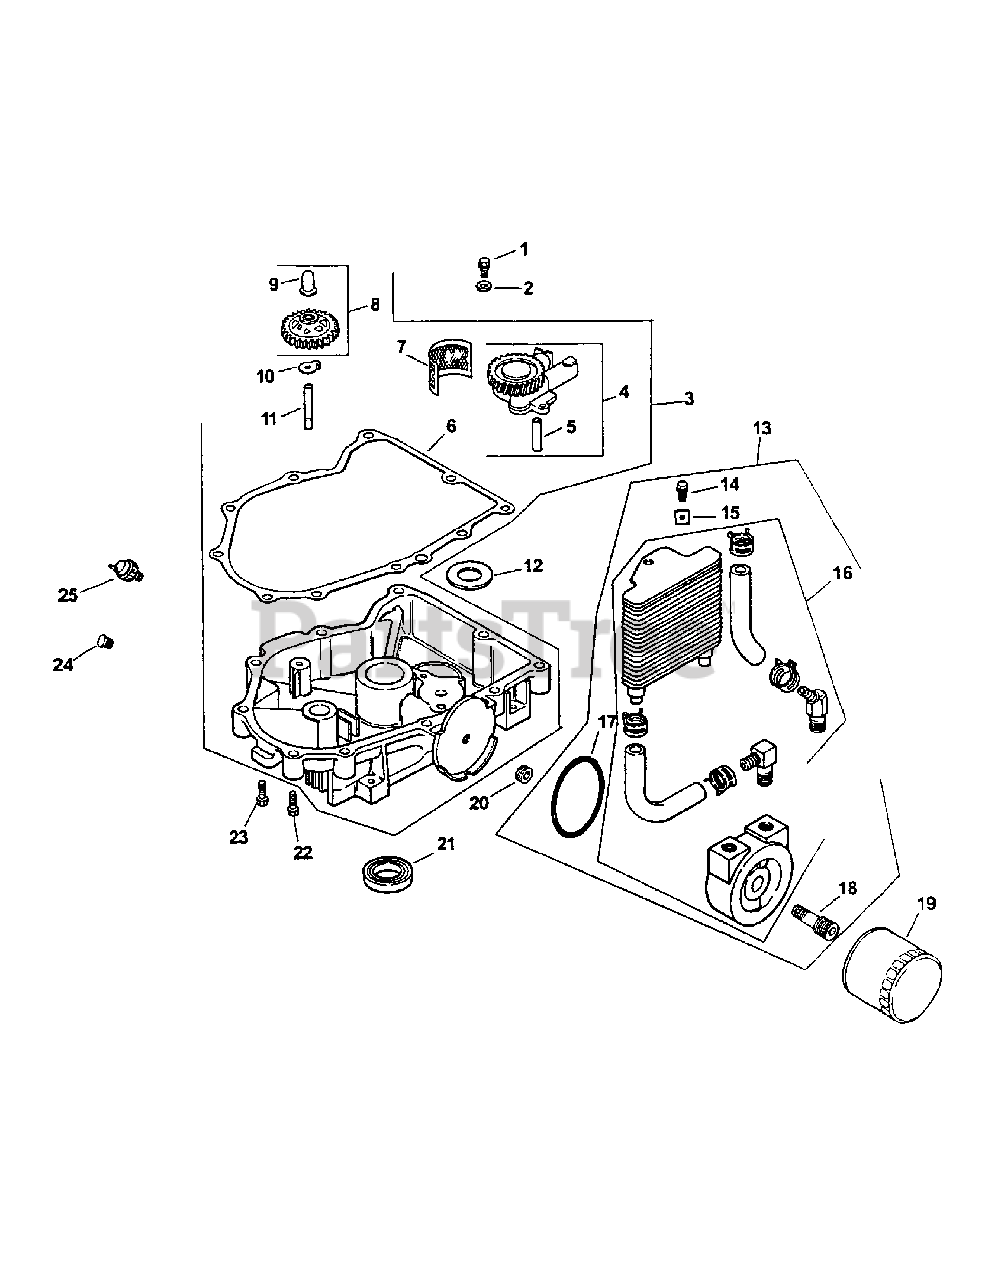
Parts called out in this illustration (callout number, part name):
1	Screw, Hex Flange
2	Washer, Plain 6mm
3	Kit, Oil Pan w/Gaskets
4	Oil Pump Assembly
5	Tube, Oil Pickup
6	Gasket, Oil Pan
7	Screen, Oil
8	Kit, Governor Gear
9	Pin, Governor Regulating
10	Tab, Locking
11	Shaft, Governor Gear
12	Shim, Thrust
13	Kit, Oil Cooler
14	Screw, Hex Cap
15	Nut, Plastic
16	Oil Cooler - Phenolic
18	Nipple, Oil Filter
19	Filter, Oil
20	Plug, Hex 3/8"
21	Seal, Oil (P.T.O. End)
22	Screw, Hex Flange
23	Screw, Hex Flange
24	Plug, Hex Head 3/8"
25	Switch, Oil Pressure
